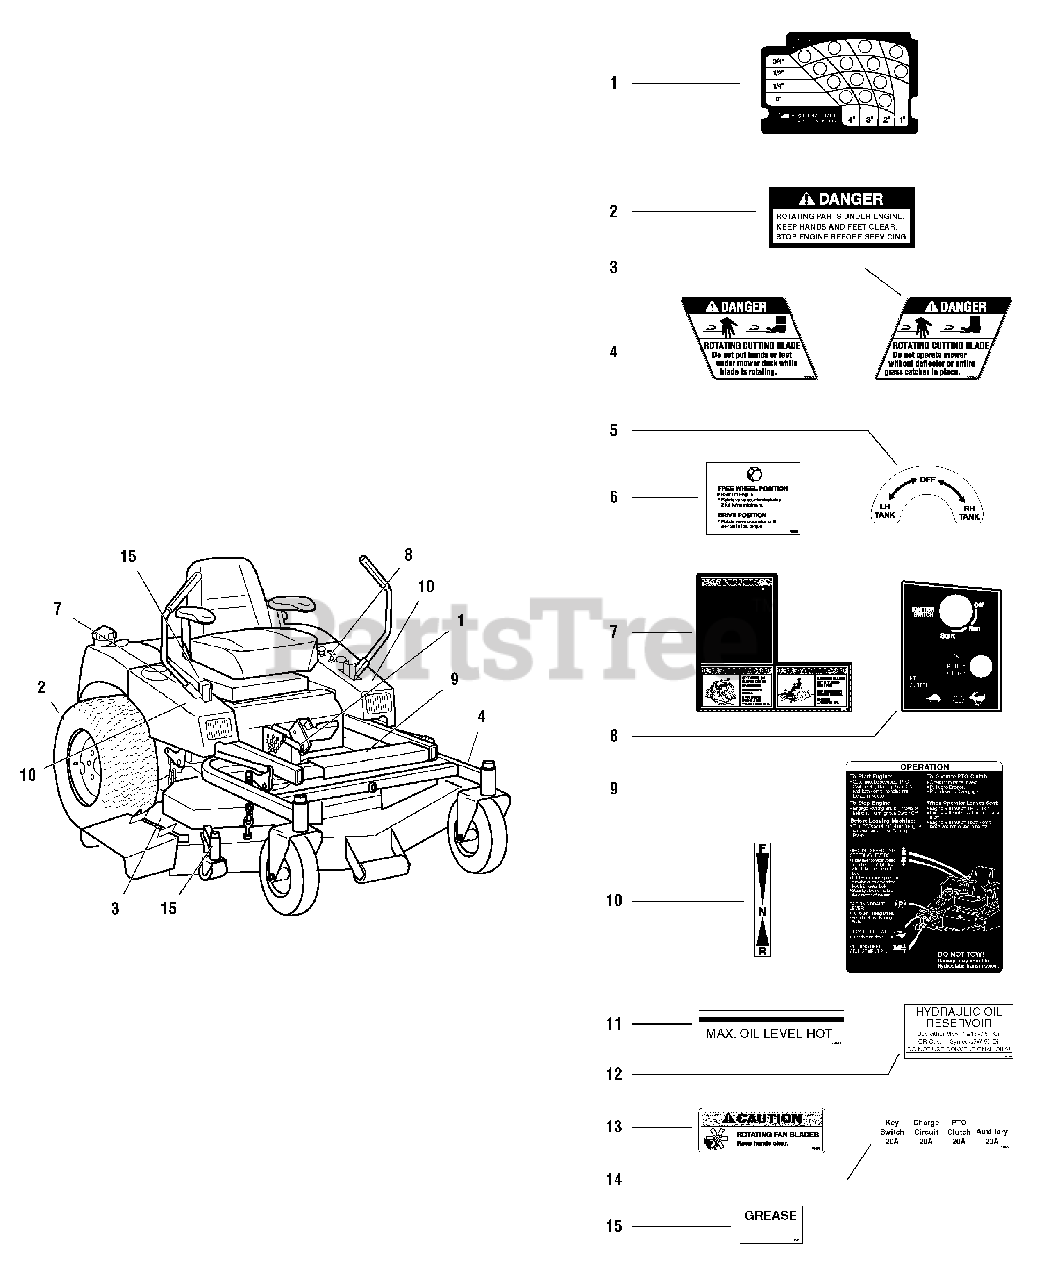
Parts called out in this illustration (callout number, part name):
1	DECAL, Deck Height
2	DECAL, Danger
3	DECAL, Danger (Chute In Place)
4	DECAL, Danger (Hand Under Deck)
5	DECAL, Fuel Shut Off
6	DECAL, Hydro Release Valve
7	DECAL, Warning/Danger
8	DECAL, Instrument Panel
9	DECAL, Operation
10	DECAL, Direction Control
11	DECAL, Max. Oil Level
12	DECAL, Oil Reservoir
13	DECAL, Caution Rotating Fan
14	DECAL, Fuse Location
15	DECAL, Grease Daily
